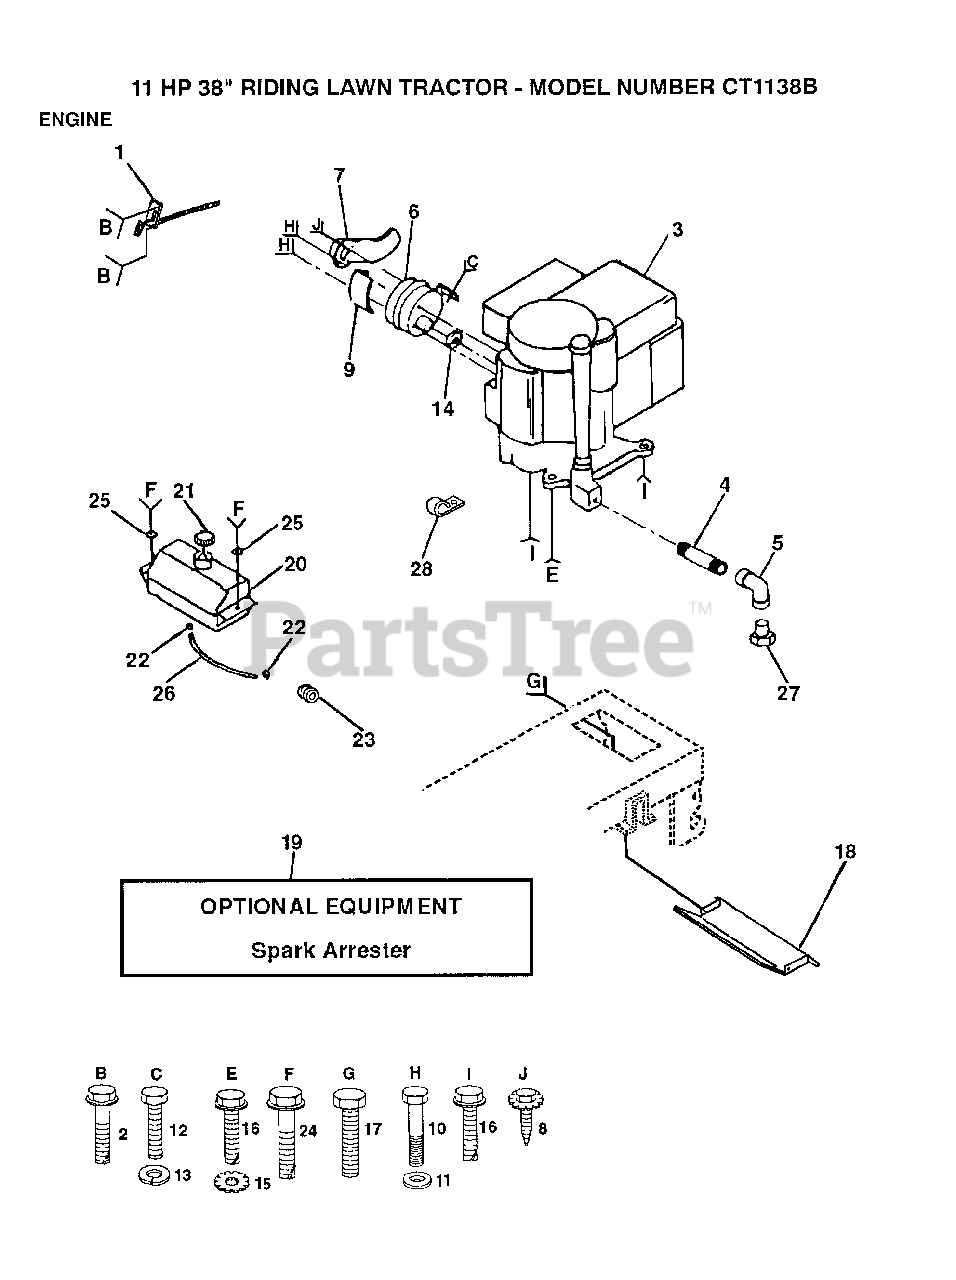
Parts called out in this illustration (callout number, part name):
1	THROTTLE CONTROL
2	SCREW LT
4	PIPE NIPPLE
5	ELBOW
6	MUFFLER LTV
7	DEFLECTOR MUFFLER
9	SHIELD HEAT LTV
10	"BOLT,HEX"
11	WASHER T
12	BOLT
13	LOCKWASHER
15	LOCKWASHER
16	SCREW
17	SCREW
18	HEAT SHIELD
20	TANK.FUEL.LT.
22	HOSE CLAMP
24	SCREW
25	WASHER GT
26	FUEL LINE T
28	CLIP T
